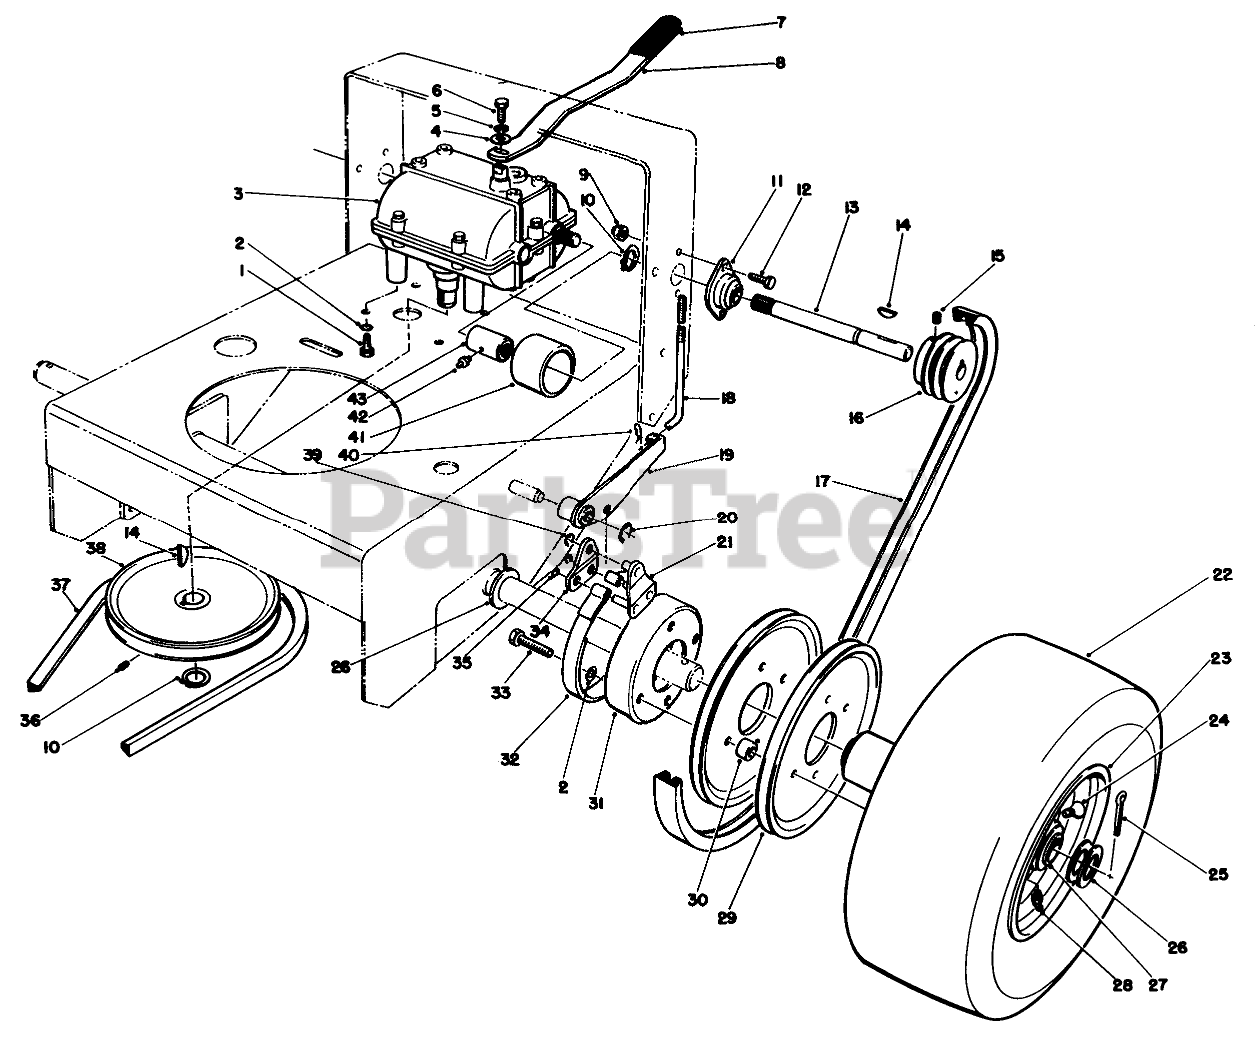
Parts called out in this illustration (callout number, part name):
1	SCREW-HH
2	WASHER-LOCK
3	Transmission
4	SPACER
5	WASHER-LOCK
6	SCREW-HH
8	SHIFT LEVER
9	NUT-LOCK, NI
10	RING-SNAP, EXTERNAL
11	Bearing-Shaft Extension
12	SCREW-HH
13	SHAFT-EXTENSION, RH
14	KEY-WOODRUFF
15	SCREW-SET, HSH
16	Pulley-Drive
17	V-BELT
18	ROD-BRAKE
19	Arm-Brake LH
20	RING-RETAINING
21	LINK-Brake
22	Tire
23	RIM & HUB ASM
24	STEM-VALVE
25	PIN-COTTER
26	WASHER-WHEEL
27	BEARING-BALL, FLANGED
28	FITTING-GREASE
29	Pulley-Wheel
30	SPACER-PULLEY
31	Drum-Brake
32	BAND-BRAKE
33	SCREW-HH
34	Plate-Link
35	RING-RETAINING
36	SCREW-SET
37	V-BELT
38	PULLEY-DRIVEN
39	RING-RETAINING, EXTERNAL
40	PIN-COTTER
41	GUARD-COUPLER
42	FITTING-GREASE
43	COUPLER
